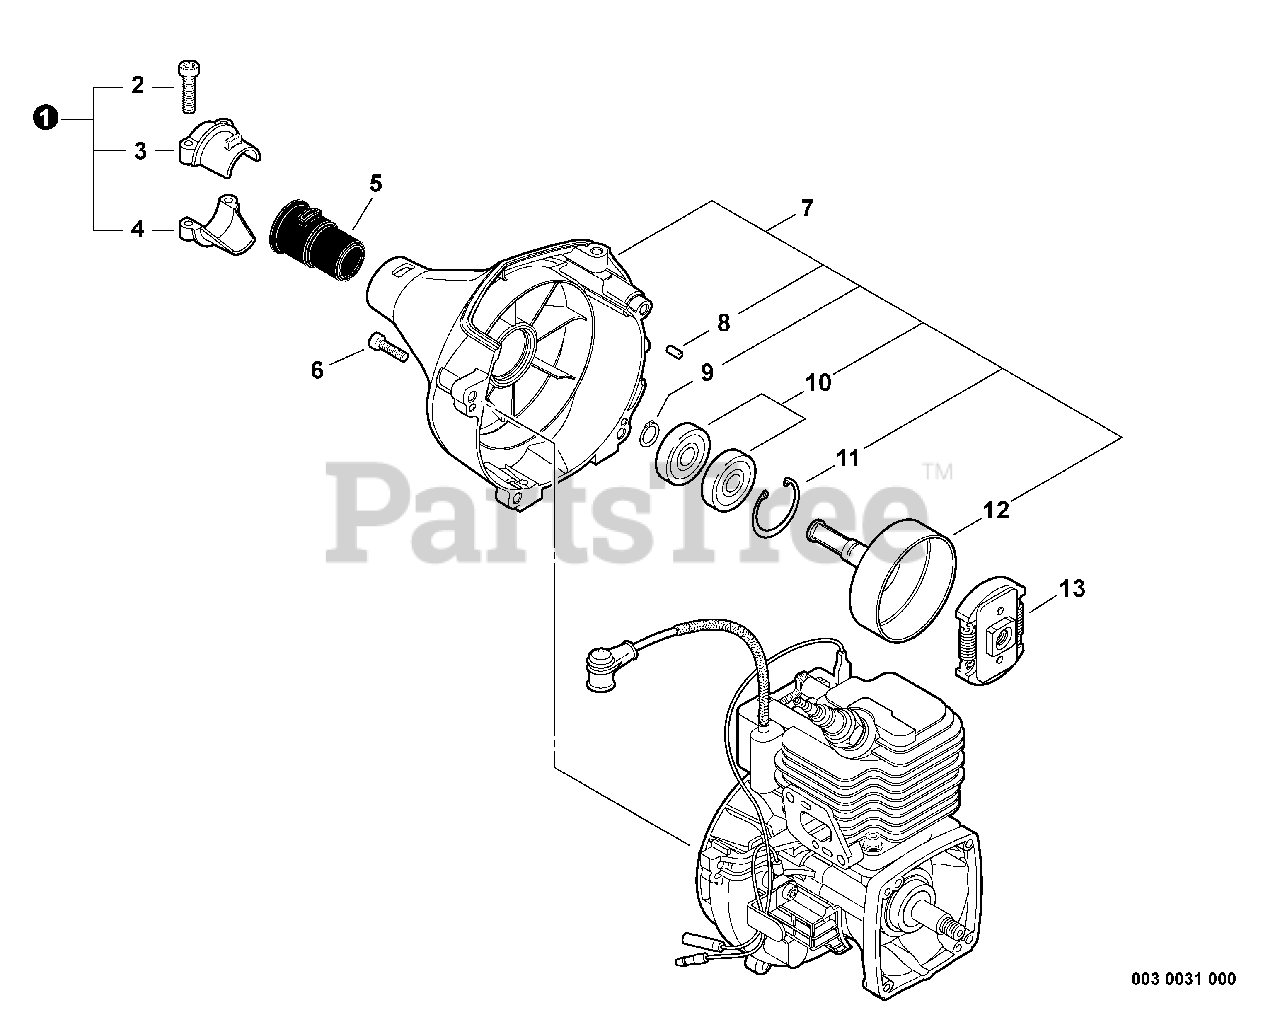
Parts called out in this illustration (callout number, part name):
1	CLAMP KIT
2	SCREW - 5X20
3	CLAMP, MAIN PIPE - UPPER
4	CLAMP, MAIN PIPE - LOWER
6	SCREW - 4X16
7	FAN CASE ASSY
8	PIN - LOCATING
9	RING, RETAINING - 12
10	BEARING, BALL - 6001
11	RING, RETAINING - 28
12	DRUM, CLUTCH
13	CLUTCH ASSY
